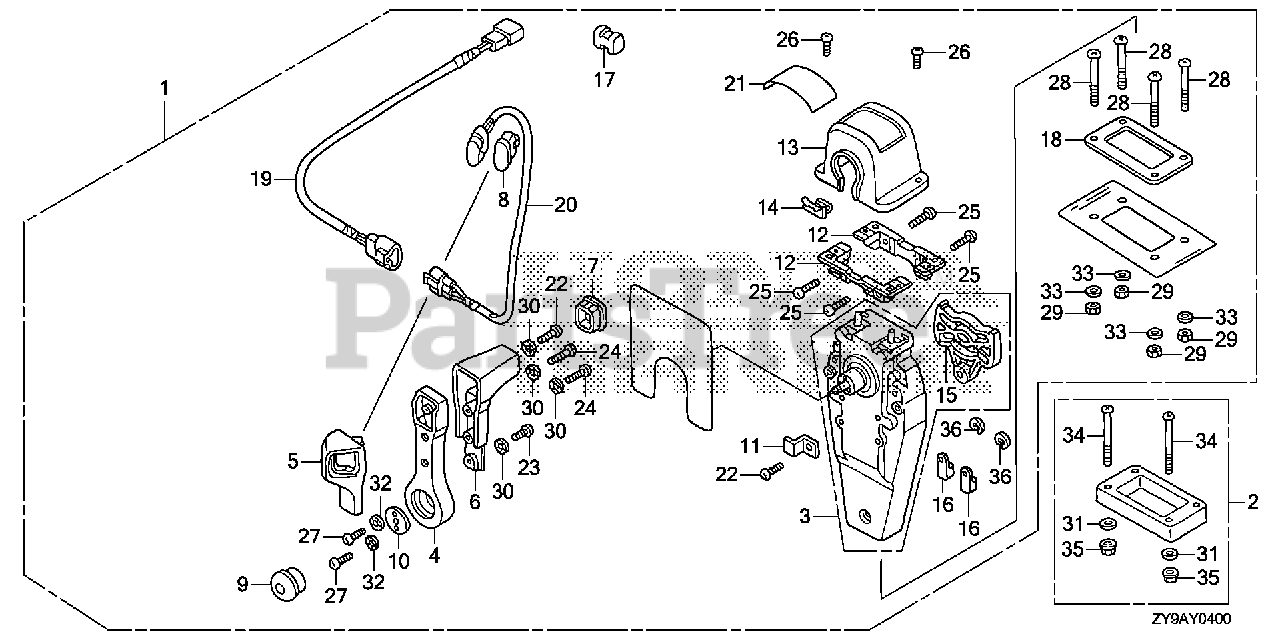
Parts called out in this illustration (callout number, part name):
1	BOX KIT, REMOTE CONTROL (TOP MOUNT SINGLE)(R)
2	SPACER KIT, REMOTE CONTROL BOX (TOP MOUNT SINGLE)
3	HOUSING ASSY., L. (INNER) (TOP MOUNT)
4	HANDLE, REMOTE CONTROL
5	COVER, L. GRIP
6	GRIP, REMOTE CONTROL HANDLE
7	CAP, GRIP
8	CAP, SWITCH
9	BUTTON, THROTTLE
10	PLATE, HANDLE
11	PLATE, CABLE CLAMP
12	BRACKET, REMOTE CONTROL HOUSING
13	HOUSING, REMOTE CONTROL BOX
14	HOUSING, LEAD
15	PLATE, DWELL
16	TERMINAL, CABLE
17	SPACER, CABLE CLAMP
18	GASKET, SINGLE
19	SUB-HARNESS ASSY., POWER TRIM-TILT (A)
20	SWITCH ASSY., POWER TRIM-TILT (A)
21	MARK, REMOTE CONTROL (SINGLE)
22	SCREW, PAN (5X16)
23	SCREW, PAN (5X10)
24	SCREW, PAN (5X20)
25	SCREW, PAN (5X18)
26	SCREW, PAN (4X10)
27	SCREW, PAN (6X18)
28	SCREW, PAN (5X40)
29	NUT, HEX. (5MM)
30	WASHER, LOCK (5MM)
31	WASHER, PLAIN (5MM)
32	WASHER, LOCK (6MM)
33	WASHER, PLAIN (5MM)
34	SCREW, PAN (5X65)
35	NUT, HEX. (5MM)
36	E-RING (6MM)
